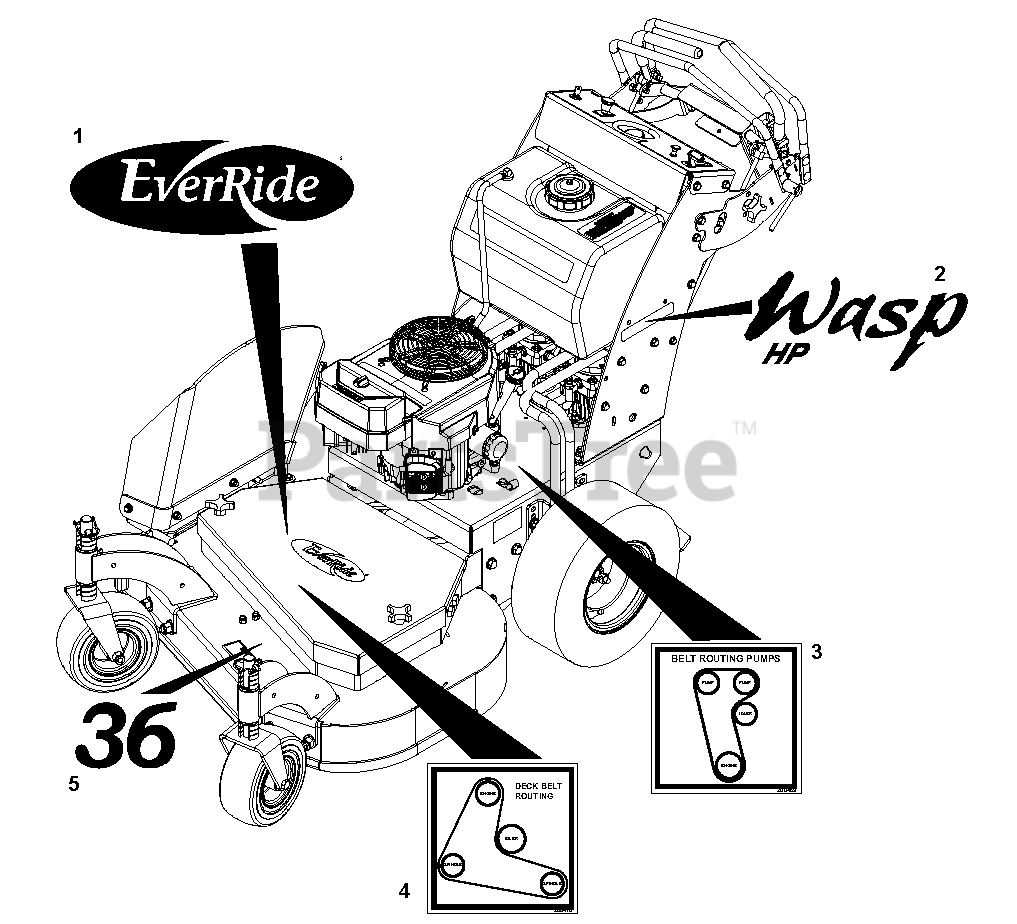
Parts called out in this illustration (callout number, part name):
1	Decal, 9" EverRide Logo
2	Decal, Wasp HP
3	Decal, Pump Belt Routing
4	Decal, 36" Deck Belt Routing (988400)
5	Decal, Deck 36" (988400)
